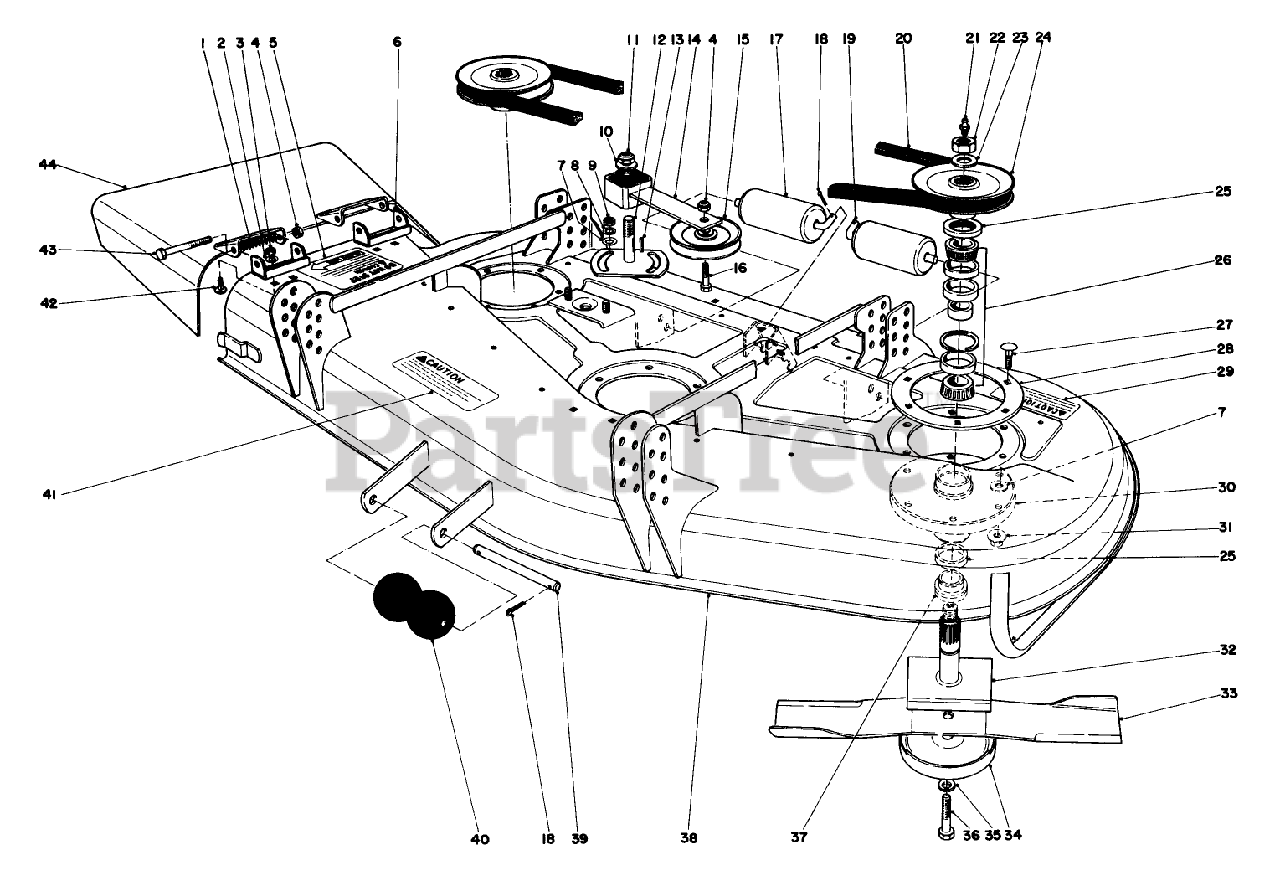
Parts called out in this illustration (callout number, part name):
1	SPRING
2	WASHER-LOCK
3	NUT-HEX
4	NUT-HEX
5	Decal-Caution
6	Bracket-Pivot
7	WASHER-FLAT
8	WASHER-LOCK
9	NUT-JAM
10	WASHER-FLAT
11	NUT-LOCK, NI
12	PLATE-IDLER
13	KEY-SQUARE
14	IDLER ARM ASM
15	Pulley
16	SCREW-HH
17	ROLLER-DECK
18	PIN-COTTER
19	SHAFT-ROLLER, REAR
20	V-BELT
21	FITTING-GREASE
22	NUT-HEX
23	WASHER
24	PULLEY AND HUB ASM
25	SEAL-OIL
26	BEARING ASM
27	SCREW-CARR
28	SUPPORT-DECK, RING
29	DECAL-CAUTION, BLADE
30	Housing-Spindle
31	NUT-HF
32	SHAFT
33	Blade
34	Cup-Scalp
35	WASHER-LOCK
36	SCREW-BLADE
37	SPACER
38	GM 52 DECK WA RO
39	SHAFT-ROLLER
40	ROLLER
41	Decal-Caution
42	SCREW-CARR
43	SCREW-HH
44	Deflector
